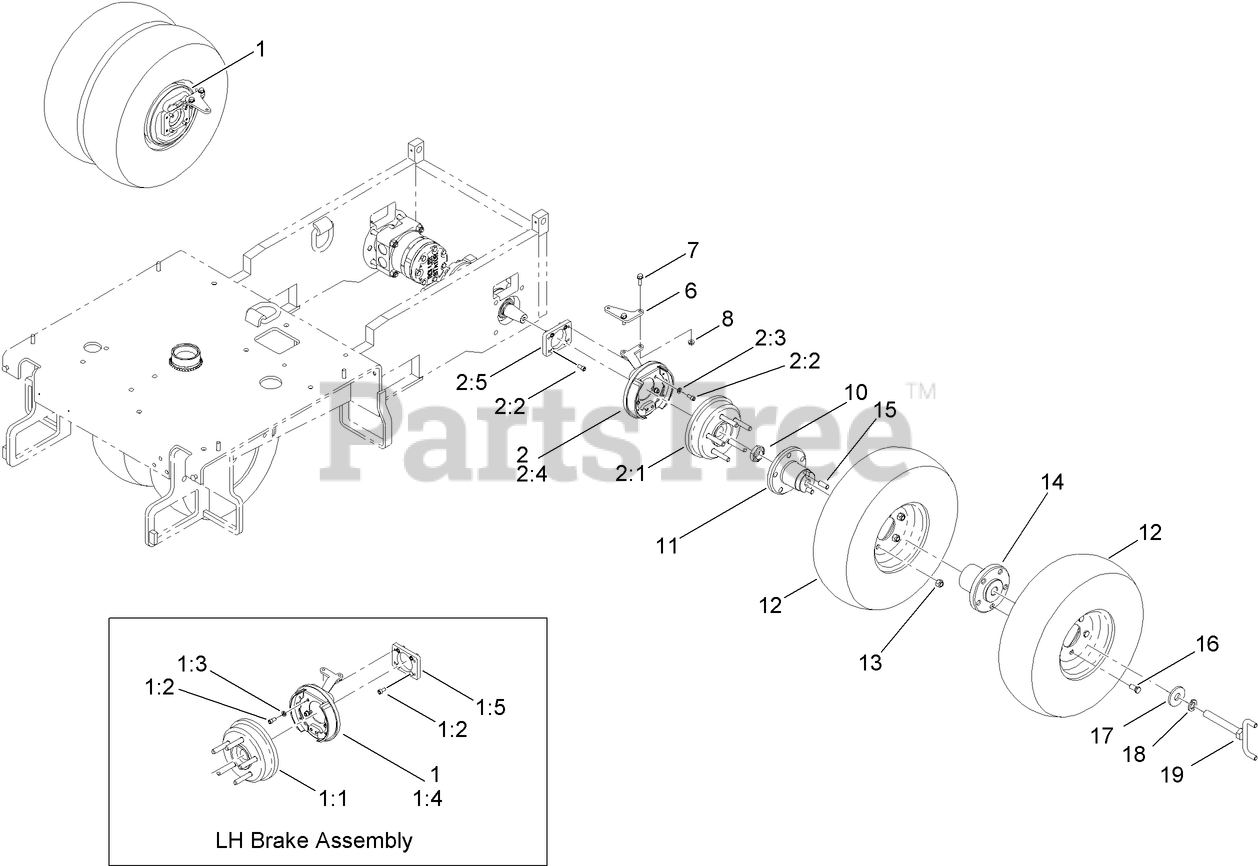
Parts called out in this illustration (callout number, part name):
1	LH BRAKE ASM
1:1	5 LUG HUB ASM
1:3	WASHER-LOCK
1:4	BRAKE-LH
1:5	BLOCK-BRAKE MOUNT
2	RH BRAKE ASM
2:1	5 LUG HUB ASM
2:3	WASHER-LOCK
2:4	BRAKE-RH
2:5	BLOCK-BRAKE MOUNT
6	PLATE-LINKAGE, BRAKE
7	SCREW-HHF
8	NUT-FLANGE
10	NUT-SHAFT
11	SPACER-WHEEL, 5 BOLT
12	WHEEL ASM (WITH FOAM)
13	NUT-LUG
14	SPACER-WHEEL
15	PIN-ROD, CONNECTING
16	BOLT-LUG
17	WASHER-FLAT
18	WASHER-LOCK
19	PIN-QUICK RELEASE
